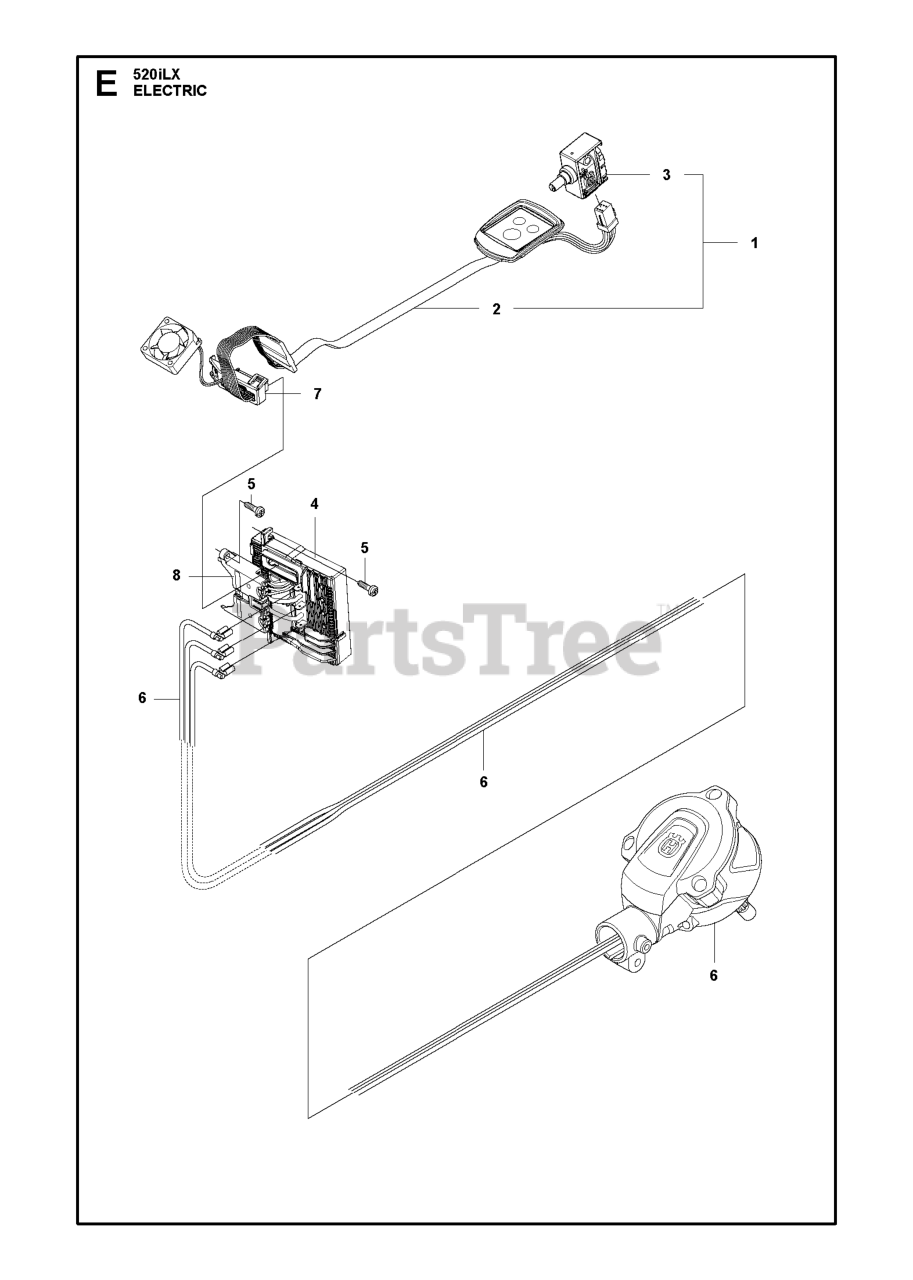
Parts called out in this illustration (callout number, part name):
1	SWITCH KIT BATTERY TRIMMER 536
2	WIRING ASSY MAIN T2
3	TRIGGER SWITCH IPX4
4	CONTROL UNIT
6	MOTOR ASSY BLDC BLADE
8	CONNECTOR BATTERY
